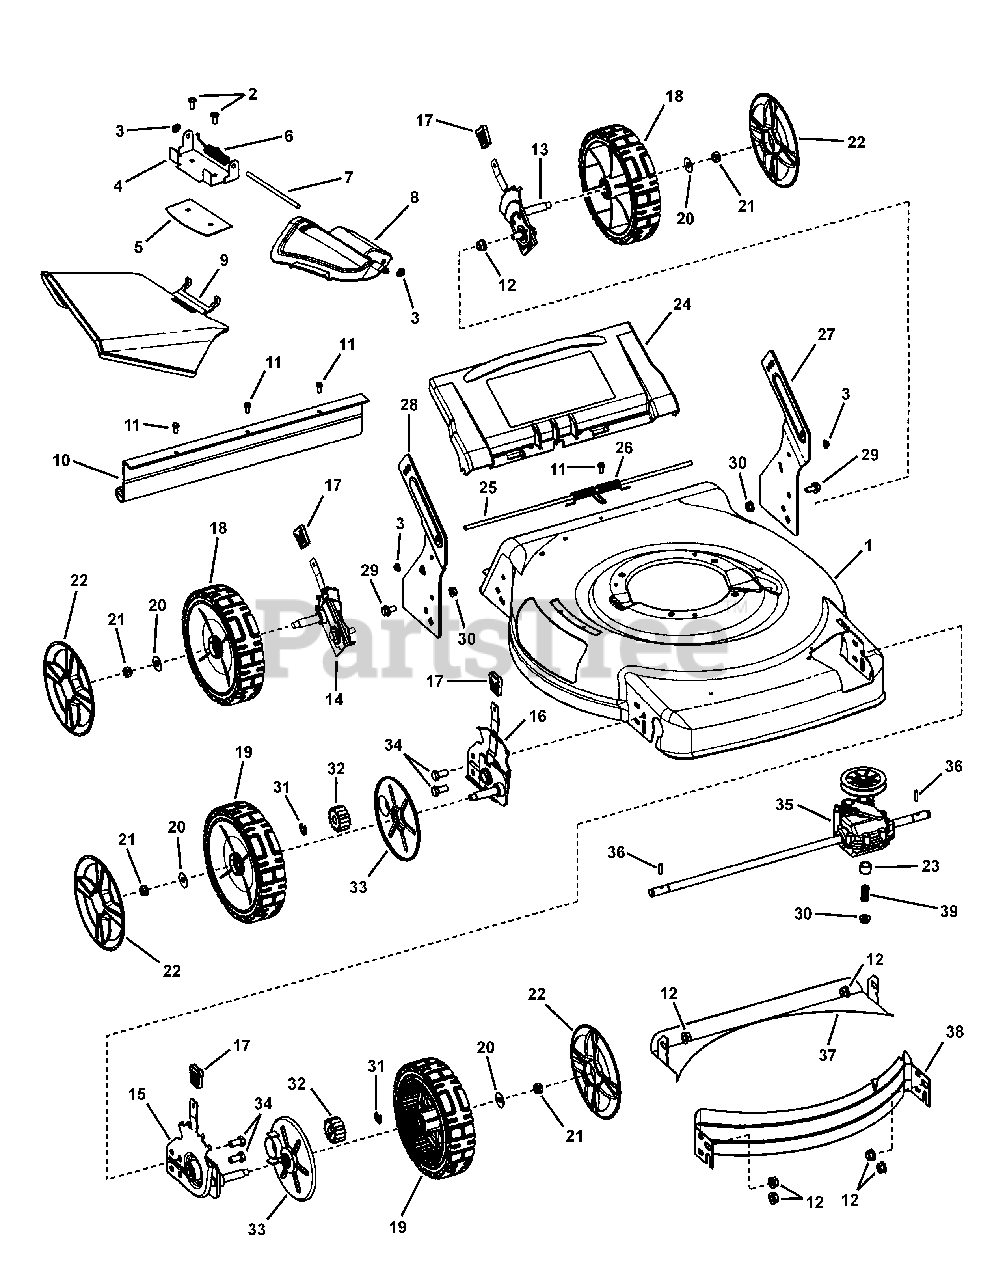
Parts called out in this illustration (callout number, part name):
1	DECK, 22" Walk, 3 N 1
2	SCREW, 1/4-20 x 11/16" Pan Head Self-Tap (Torx)
3	PUSHNUT 1/4"
4	BRACKET, Chute
5	PLATE, Mulch, 22" RB Scott's
6	SPRING, Chute (Torsion)
7	ROD, Pivot (1/4" Dia. x 5.55")
8	COVER, Mulch, Plastic, Black
9	SIDE CHUTE, Plastic, Black
10	GUARD, Rear
11	SCREW, #10-24 x 1/2" Hex Washer Self-Tap (Sems)
12	NUT, 3/8-16 Hex Flange Lock, YZ
13	* ASSY, Height-Of-Cut, Left Rear, 22" WBM
14	* ASSY, Height-Of-Cut, Right Rear, 22" WBM
15	* ASSY, Height-Of-Cut, LF, 22" WBM, Propelled
16	* ASSY, Height-Of-Cut, RF, 22" WBM, Propelled
17	GRIP, Height Latch - Black (1.7" Wide)
18	ASSY, Wheel & Bearing, 8 x 2 Idle, DW Tread
19	ASSY, Drive Wheel & Bearing, 8 x 2, DW Tread
20	WASHER, 1" O.D. x .387 I.D. Flat
21	NUT, 3/8-16 Hex Center Lock, YZ
22	HUBCAP, Black
23	SPACER, .526" ID, .840" OD, .502" Wide
24	DOOR, 22" Rear
25	ROD, Pivot, Rear Door (1/4" Dia. X 17-1/2")
26	SPRING, Torsion, Rear Door, 22" WBM
27	BRACKET, Lower Handle, LH, 22" WBM
28	BRACKET, Lower Handle, RH, 22" WBM
29	BOLT, 5/16-18 x 5/8" Hex Flange Lock, YZ
30	NUT, 5/16-18 Flange Lock, YZ
31	RING, External Retaining
32	GEAR, Pinion, 22" WBM, Front Wheel Drive
33	DUST SHIELD, Forward, 22" WBM
34	SCREW, 3/8-16 x 3/4" Hex Head Cap, GR 5, YZ
35	TRANSMISSION, 22" WBM Single Speed, Front Wheel Drive
36	DRIVE PIN, 22" WBM, Front Wheel Drive
37	BAFFLE, Rear, 22" Deck
38	BAFFLE, Front, 22" WBM
39	SPRING, Compression
